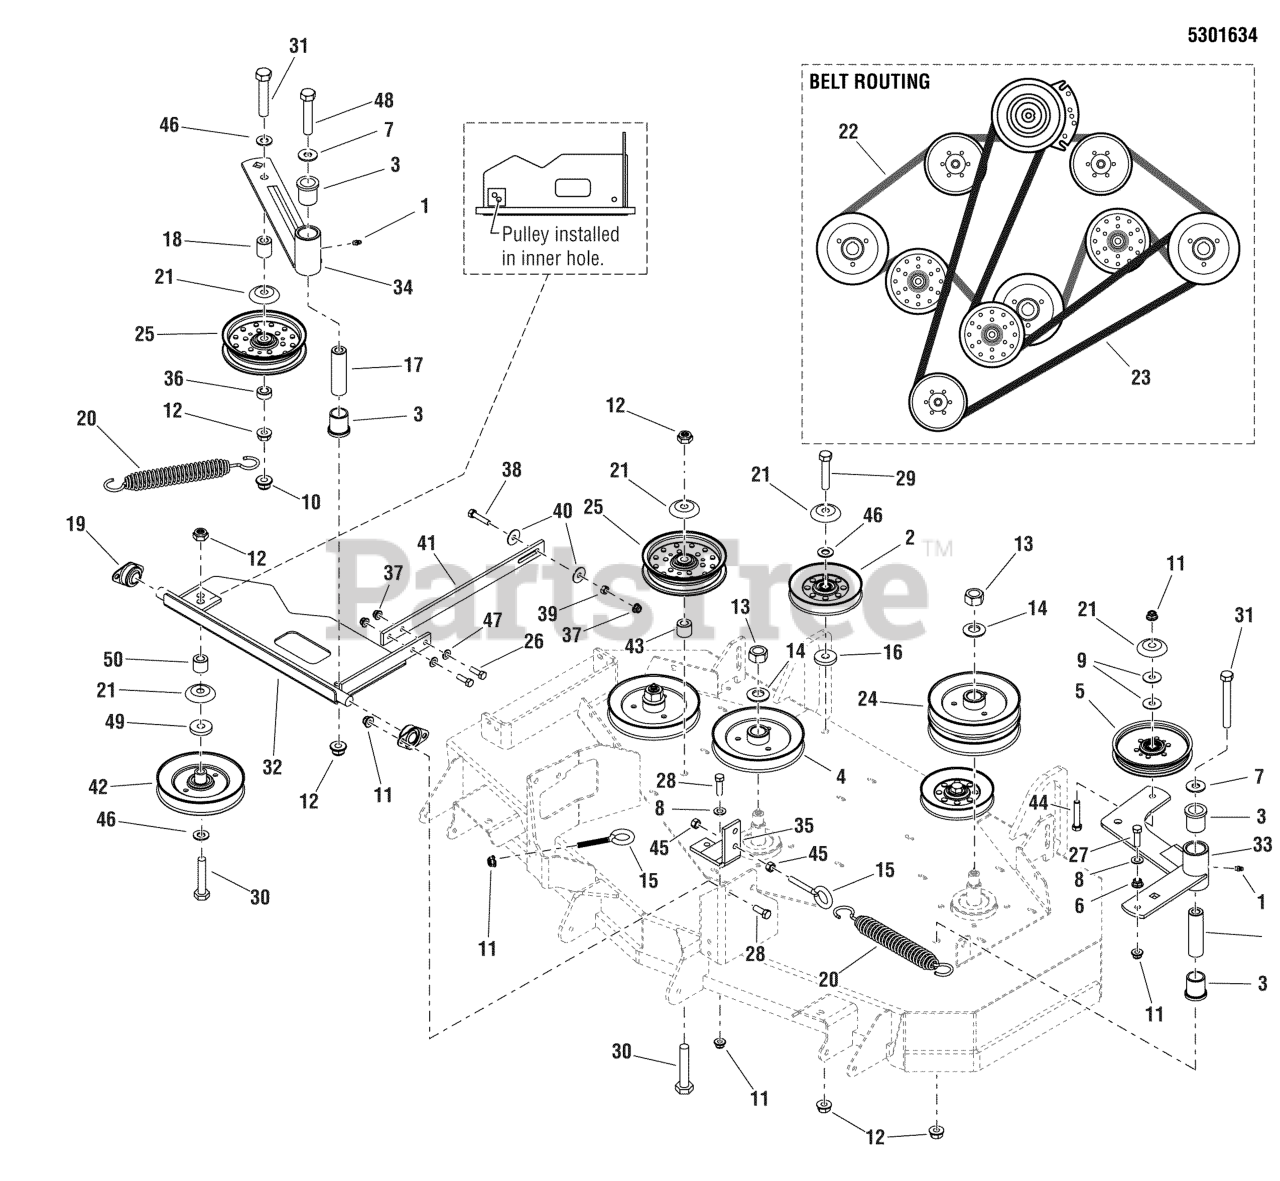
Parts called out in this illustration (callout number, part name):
1	GREASE FITTING, 1/4-28 STRAIGHT
2	PULLEY-IDLER-V, 4.85OB, .506ID, .94W,STL
3	BUSHING, FLANGE
4	PULLEY, 5.540OB X .985ID, SINGLE B-SEC
5	PULLEY-IDLER, 5.00OD, .385ID, .75W, STL
6	NUT, 3/8-16 HEX SERRATED FLANGE
7	WASHER, 1/2 USS
8	WASHER, 3/8 SAE
9	WASHER, .390 X 1.38 X .109, YZ
10	NUT, 1/2-13 HEX SIDE LOCK
11	NUT, 3/8-16 HEX NYLOCK FLANGE
12	NUT, Hex Flange, Nylock, 1/2-13
13	NUT, 3/4-16 HEX
14	WASHER, 3/4 BELLEVILLE
15	EYEBOLT, 3/8-16 X 4, 2.13THRD, .75EYE, C
16	WASHER, .53 X 1.50 X .25
17	SPACER, .52 X 1.00 X 3.50
18	SPACER, .52 X 1.00 X 1.15
19	BEARING, BRONZE FLANGE, 3/4"
20	SPRING, EXTENSION, SWIVEL, SHORT HOOK
21	SHIELD, PULLEY BEARING
22	BELT, BP-SEC, 94.10EL, LG ARAMID, WRPD
23	BELT, BP-SEC, 108.2EL, ARAMID, WRPD
24	PULLEY, DOUBLE, 5.54" OVER
25	PULLEY, IDLER, 5" OD, 1"FACE, 5.75 FL
26	BOLT, 5/16-18 X 1 GD5 YZ
27	BOLT, 3/8-16 X 1-1/4" GD5 CZ
28	BOLT, 3/8-16 X 1" GD5 CZ
29	BOLT, 1/2-13 X 2-1/2" GD5 CZ
30	BOLT, 1/2-13 X 2-3/4 GD5 CZ
31	BOLT, 1/2-13 X 4" GD5 CZ
32	WELD, IDLER MOUNT PLATE - RED
33	ASSM, IDLER ARM, EVO 48 (5404925B)
34	ASSM, IDLER ARM, EVO 36 (5405003B)
35	WELD, ANCHOR EYEBOLT - RED
36	SPACER, .52 X 1.00 X .44
37	NUT, 5/16-18 HEX NYLOCK FLANGE
38	BOLT, 5/16-18 X 1-1/2 GD5 YZ
39	NUT, 5/16-18 HEX
40	WASHER, 5/16 FENDER
41	BAR, 1/4 X 1.00 X 15.5
42	PULLEY, 6" DEEP GROOVE, COMPENSATOR
43	SPACER, .52 X 1.00 X .88
44	BOLT, 3/8-16 X 2, GD5, CZ
45	NUT, 3/8-16 HEX
46	WASHER, 1/2 SAE
47	WASHER, 5/16" SAE
48	BOLT, 1/2-13 X 5-1/2 GD5 YZ
49	SPACER, .52 X 1.00 X .22, PM, CZ
50	SPACER, .52 X 1.00 X .75
